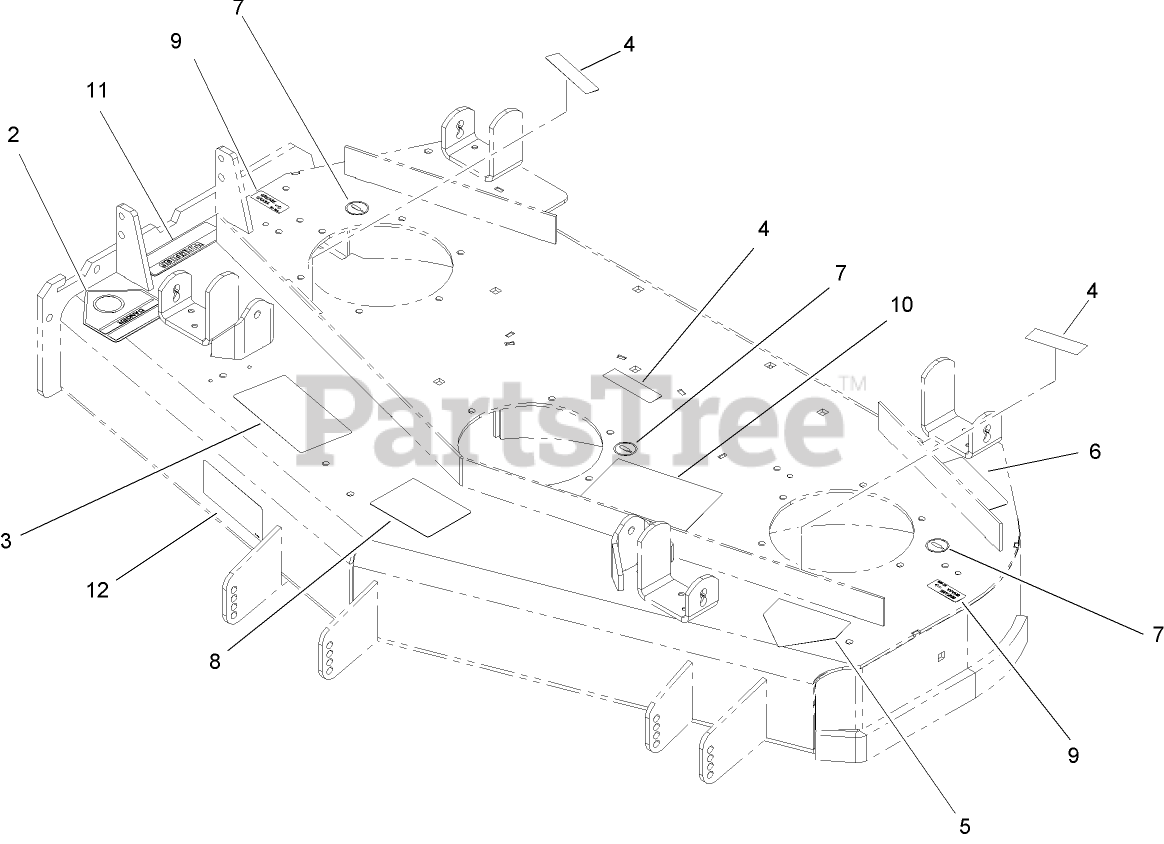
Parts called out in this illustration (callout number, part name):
2	DECAL-DANGER
3	DECAL-DANGER, THROWN OBJECT
4	DECAL-COVER, MISSING
5	DECAL-DANGER
6	DECAL-TORQUE
7	DECAL-GREASE
8	DECAL-SCALP, ANTI
9	Decal-Grease
10	DECAL-AID, SERVICE
11	DECAL-WARNING
